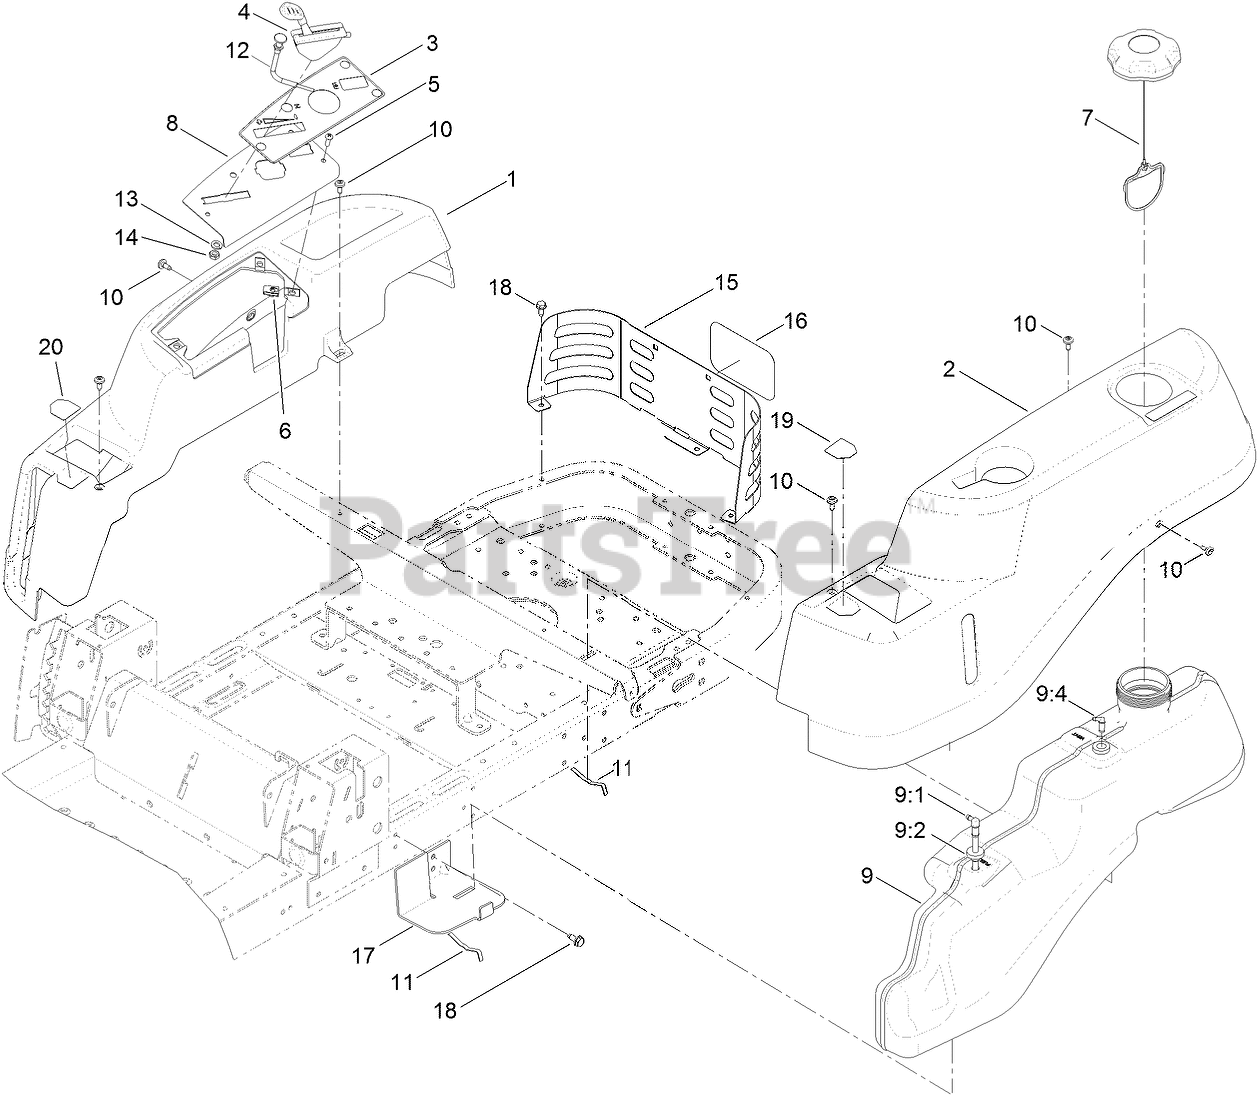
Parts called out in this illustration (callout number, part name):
1	POD-RH
2	POD-LH
3	DECAL-PANEL, CONTROL
4	CABLE-THROTTLE
5	SCREW-PRH
7	CAP-FUEL, RATCHETING
8	PLATE-CONTROL
9	FUEL TANK ASM
9:1	CONNECTOR-ELBOW, 90 DEG
9:2	BUSHING
9:4	FITTING-PLASTIC
10	SCREW-SHOULDER
11	SPRING
12	CABLE-CHOKE
13	WASHER-LOCK
14	NUT-HJ
15	GUARD-REAR
16	DECAL
17	SUPPORT-TANK, FRONT
18	SCREW-HWHTF
19	DECAL-CONTROL LEVER, LH
20	DECAL-CONTROL LEVER, RH
